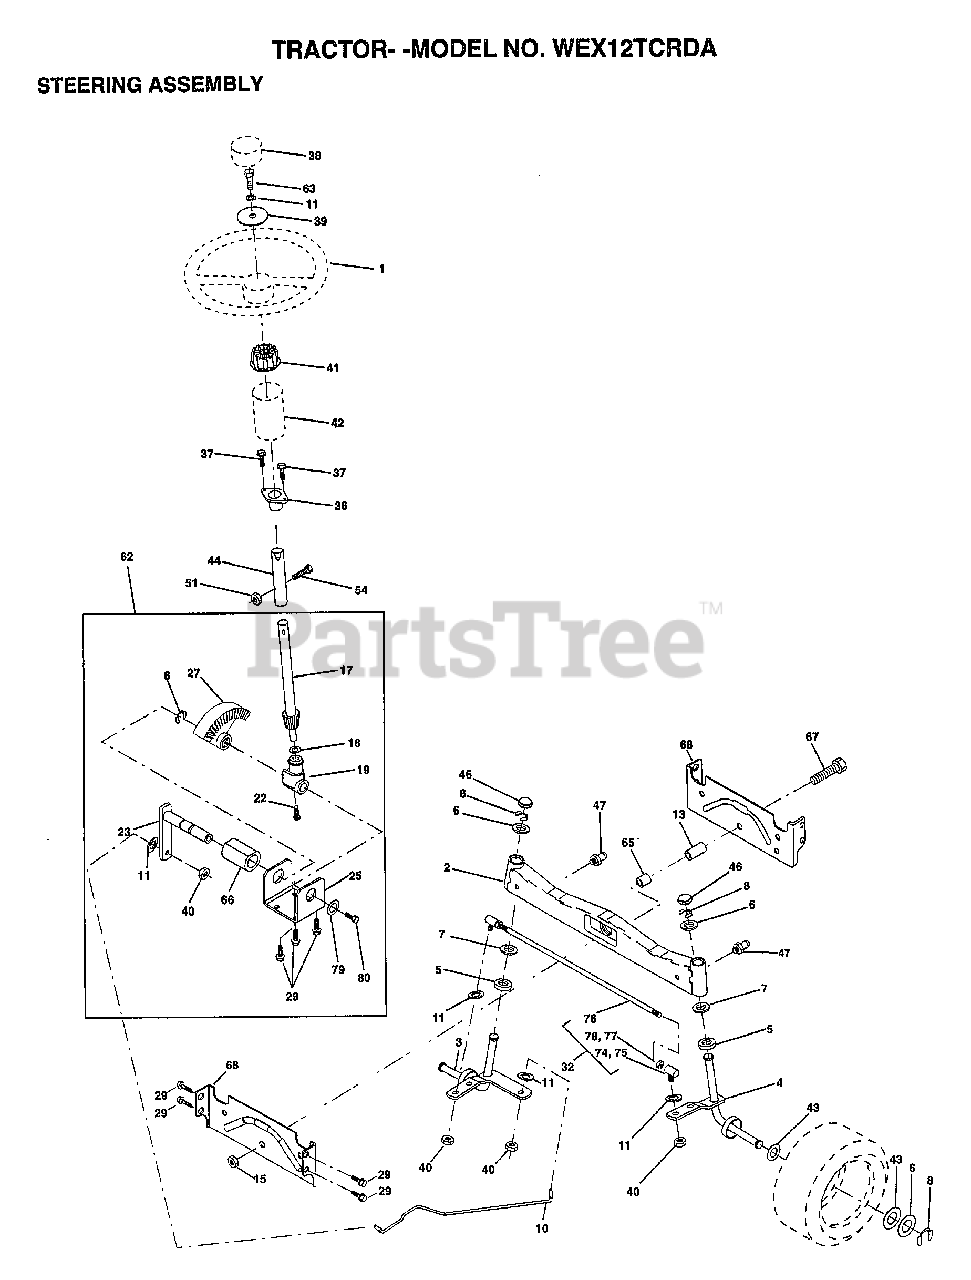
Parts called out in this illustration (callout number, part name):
1	WHEEL STR AYP BLK
3	"SPINDLE ASM,LH"
4	"SPINDLE ASM,RH"
5	WASHER .T
6	WASHER
7	WASHER
8	RING
10	LINK.DRAG
11	LOCKWASHER
13	BEARING.FRT.SPACER.AXLE
15	"NUT-LOC,FLANGE LT"
17	SHAFT ASM STEERIN
18	THRUST WASHER
19	SUPPORT.SHAFT.STEER
22	SCREW.HX.WSH.HD
23	SHAFT.ASM.PITMAN
25	BRKT-STEERING
27	GEAR SECTOR
29	SCREW
32	ROD.ASM.TIE.BALL
36	BUSHING.STEERING
37	"SCREW-TT,10-32 FL"
38	CAP STEER AYP
39	WASHER T
40	GRIPCO NUT
41	ADAPTER LT
42	BOOT.STEER.PL
43	WASHER
44	EXT SHAFT STEERIN
46	CAP
47	ZERK M
51	NUT
54	BOLT
62	KIT.STEER.ASM
63	BOLT
65	SPACER AXLE
66	"BEARING-ARM,PITMA"
67	BOLT
68	BRACE AXLE
74	JOINT.RH
75	JOINT.LH
77	NUT
78	NUT
79	WASHER
80	BOLT.HX.NYLON3/8-16X3/
